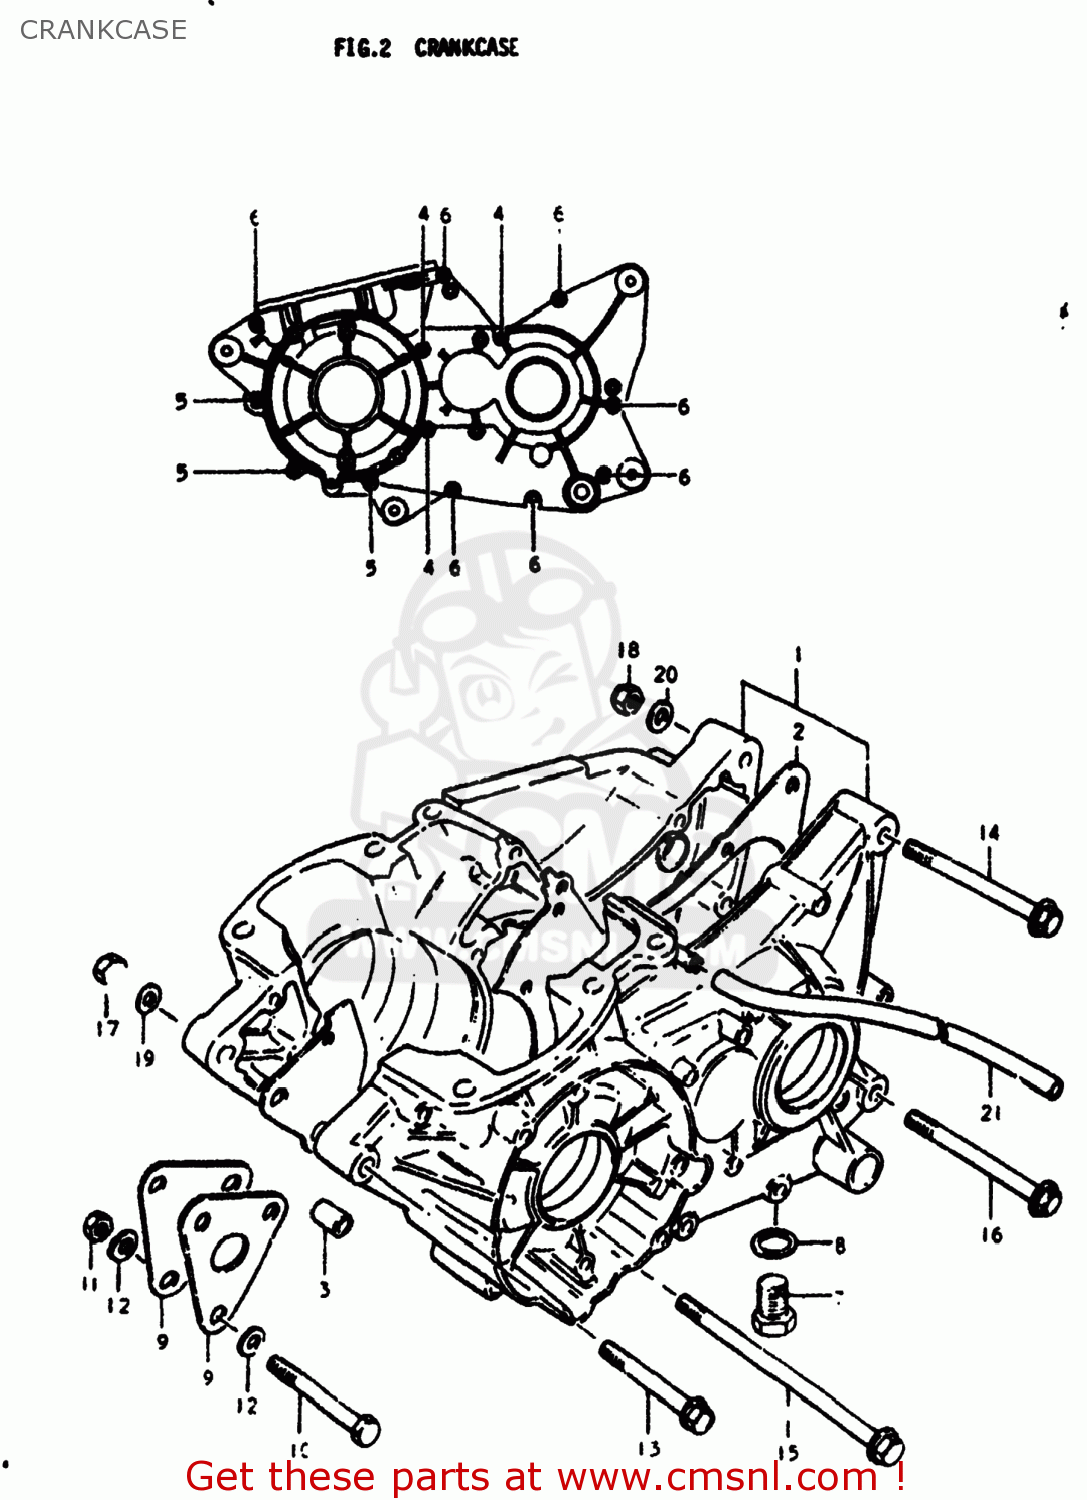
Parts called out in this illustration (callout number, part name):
1	CRANKCASE SET
2	GASKET,CRANKCASE (MCA)
3	PIN
4	SCREW 6X60
5	SCREW
6	SCREW
7	PLUG
8	GASKET(14X19.2X2) (NAS)
9	PLATE,ENGINE MOUNTING
10	BOLT
11	NUT
12	WASHER
13	BOLT
14	BOLT
15	BOLT
16	BOLT(8X80)
17	NUT
18	NUT
19	WASHER
20	WASHER
21	HOSE
